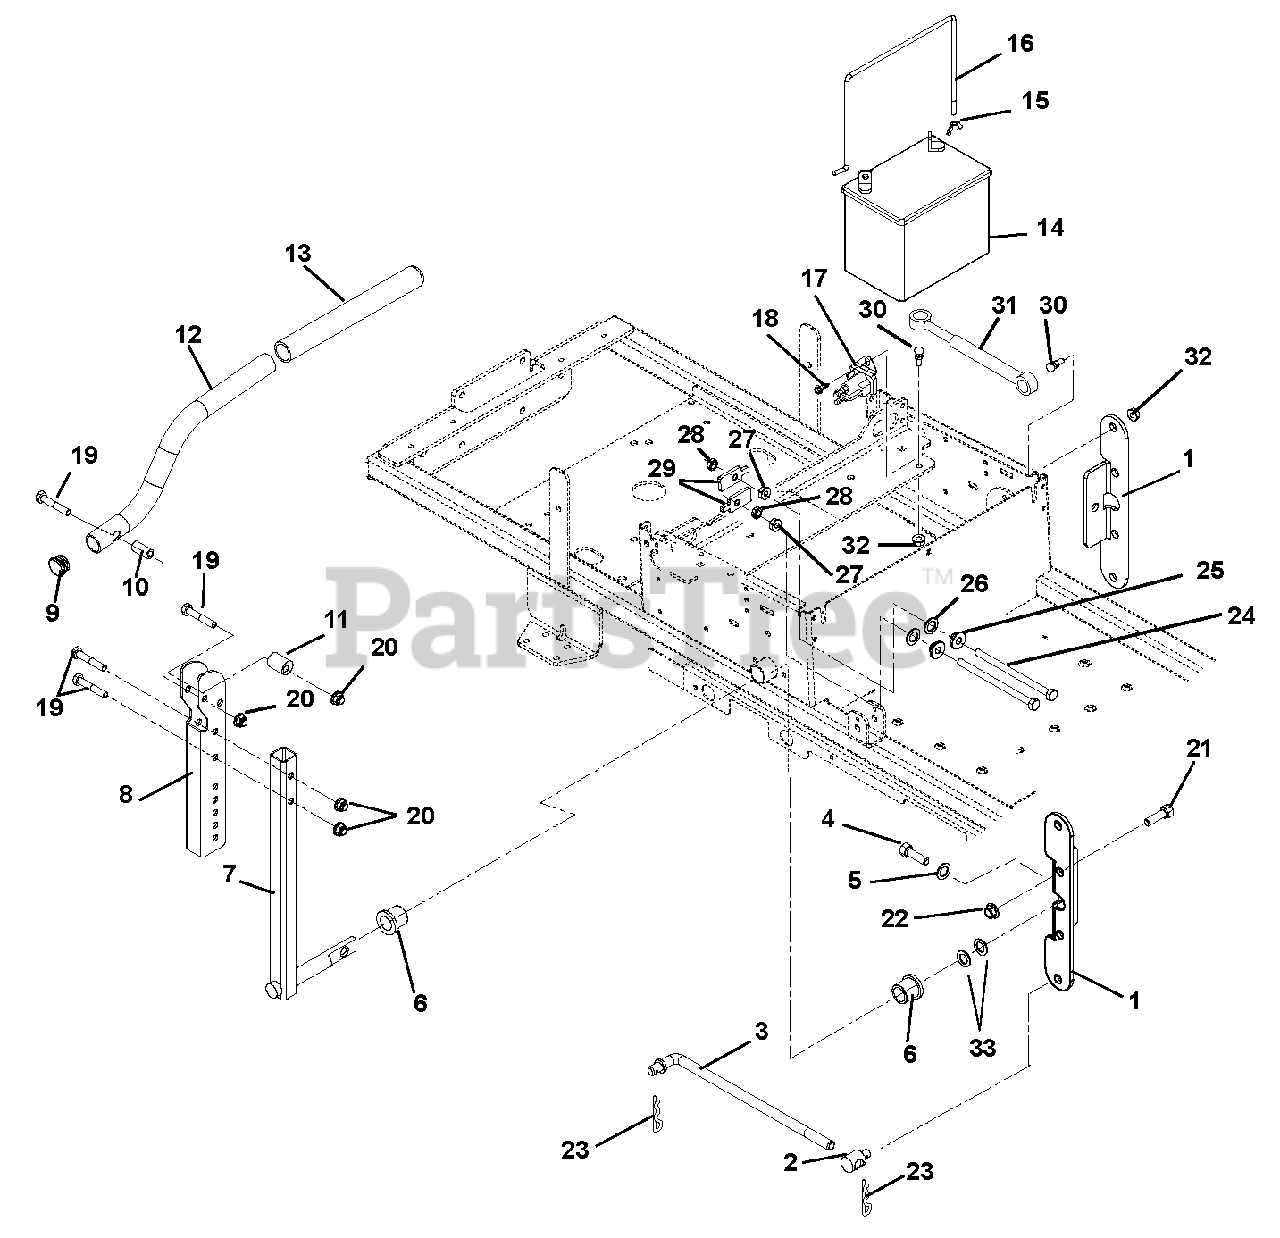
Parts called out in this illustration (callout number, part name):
1	Control Link
2	Pivot, Rod
3	Link, Wireform
4	Bolt, .38-16 x 1 Grade 8 EP30
5	Washer, Flat Steel .390 x 1.5 x .125
6	Bushing, 1.00 x .75 x 1.00
7	Weldment, Control Arm
8	Channel, Upper Handlebar
9	Caplug, Handlebar
11	Eccentric
12	Handlebar
13	Grip, Handlebar
15	Nut, Lock Wing .250-20
16	Battery Rod
17	Solenoid
18	Screw, Tap .250-20 x .37
19	Bolt, Hex .31-18 x 1.75 Grade 5
20	Nut, 5/16-18 Flange Nyloc
21	Bolt, Hex .38-16 x 1.25 Grade 5
22	Nut, Hex Jam .375-16
23	Pin, Hair Internal .08 x .18 x 1.18
24	Bolt, Hex 5/16-18 x 5 Grade 2
25	Bushing, Flange .312 x .500 x .344 x .880
26	Washer, Flat Steel .52 x .827 x .062
27	Nut, Spin Lock-Flange .312-18
28	Nut, Jam .312-18
29	Stop Tab
30	Stud, Ball
31	Damper, Control
32	Nut, Locking Top Flange .31-18
33	Washer, Flat Steel .755 x 1.25 x .125
